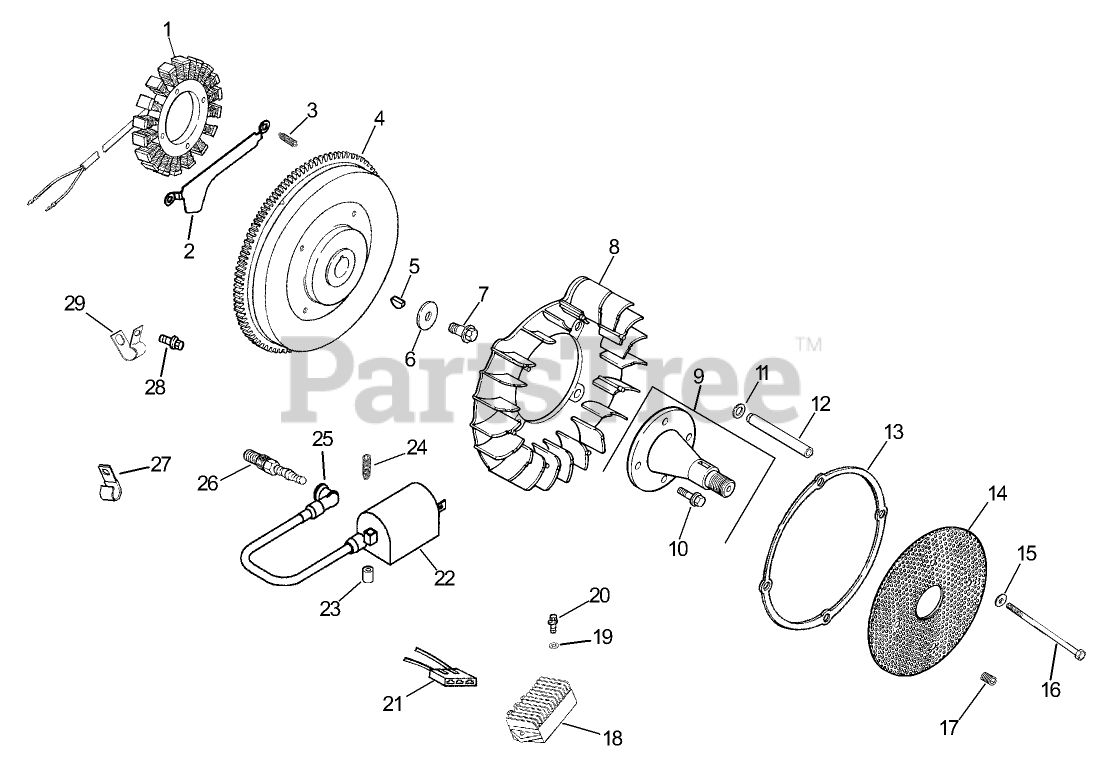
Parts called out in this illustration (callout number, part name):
1	Kit, stator w/connectors (Includes 2,40)
2	Screw-Tapping
3	Bracket-Wire, Stator
4	Flywheel
5	KEY (3/16 X 5/8)
6	WASHER-FLAT (13/32)
7	SCREW-FLANGE (M10X1.5X45)
8	Fan
10	Screw-HF (M8x1.25x25)
11	Washer-Spring (10MM)
12	Spacer
13	Ring-Support
14	Kit, front drive shaft (Includes 10)
14	Screen-Grass
15	WASHER-FLAT (1/4)
16	Screw-HH (M6x1.0x100)
17	Screw-Set (10-24X.25)
18	Rectifier-Regulator (15 amp)
19	WASHER-FLAT (.188)
20	SCREW-PHL HD (11-16X.88)
21	Connector (3 contact)
22	Coil-Ignition
23	Spacer
24	Screw-Tapping
25	Spark Plug Boot ASM
26	Spark Plug
27	Clip-Cable
28	SCREW-FLANGE, THREAD FORMING (M5X0.8X16)
29	Clamp-Hose
